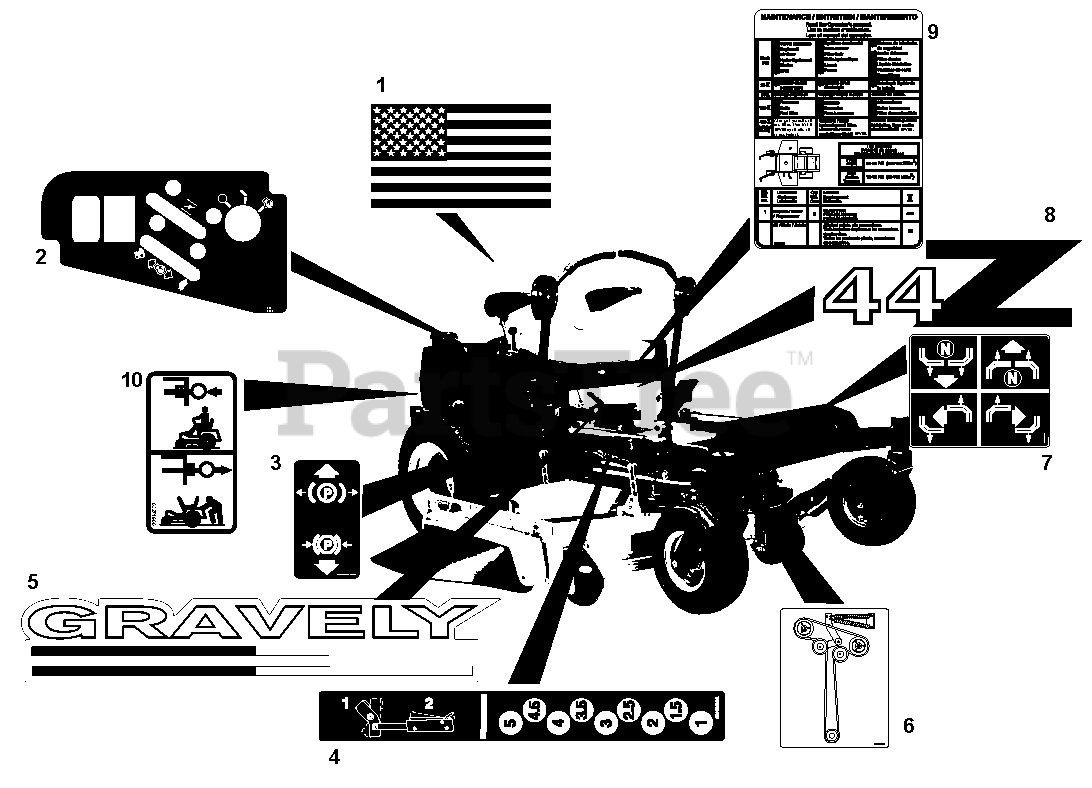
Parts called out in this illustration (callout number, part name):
1	Decal, American Flag
2	Decal, Control Panel (SN 000200 - 000799)
3	Decal, Parking Brake Lever
4	Decal, Height of Cut
5	Decal, ZT Hood
6	Decal, Belt Diagram
7	Decal, Instructional Steering
8	Decal, PM 44Z (035)
9	Decal, Maintenance Instructions
10	Decal, Transmission Disconnect
